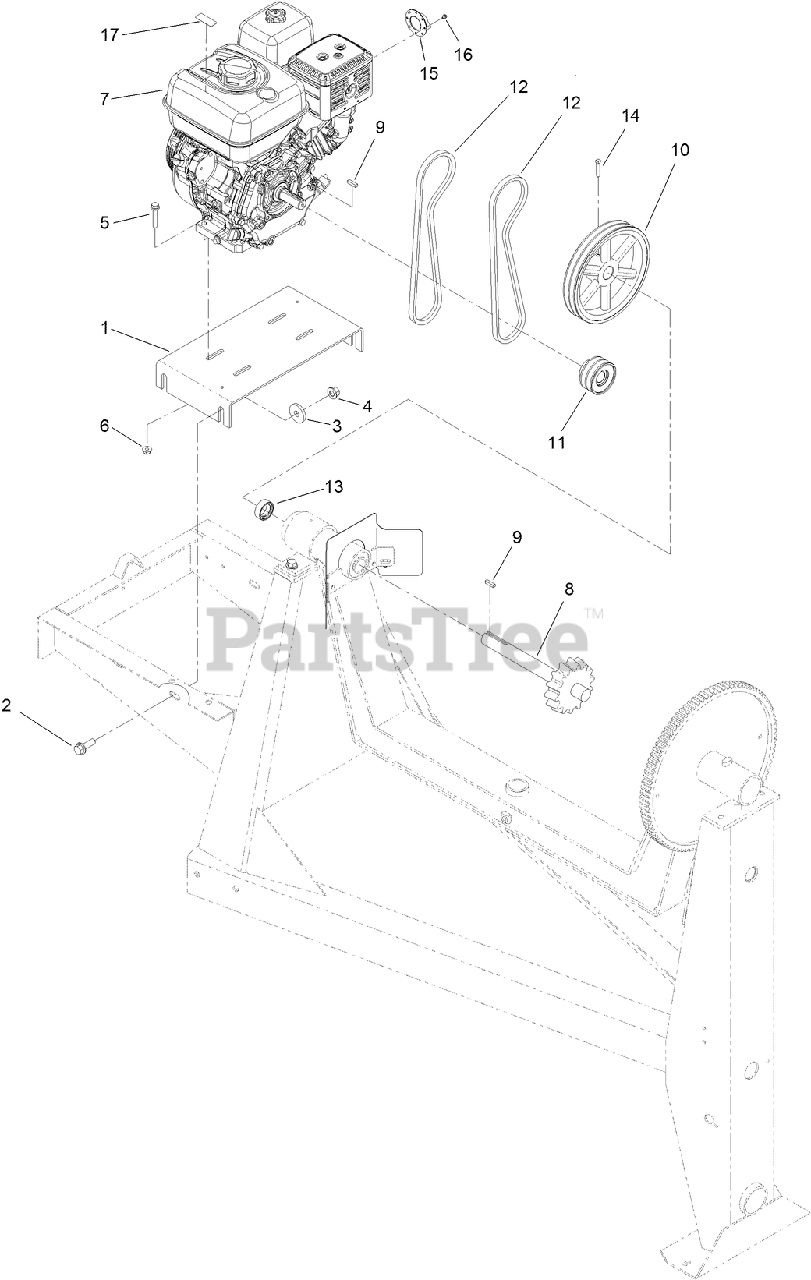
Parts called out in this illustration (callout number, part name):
1	BASE-ENGINE, 95CM
2	SCREW-HHF
3	WASHER-FLAT
4	NUT-LOCK
5	SCREW-HHF
6	NUT-HF, NI
7	ENGINE-HONDA, GX240
8	SHAFT-DRIVE
11	SHEAVE
12	BELT-V
13	COLLAR-LOCKING
14	SCREW-SET
15	DEFLECTOR-EXHAUST, HONDA
16	SCREW-HWH
17	DECAL-WARNING, ETHANOL
